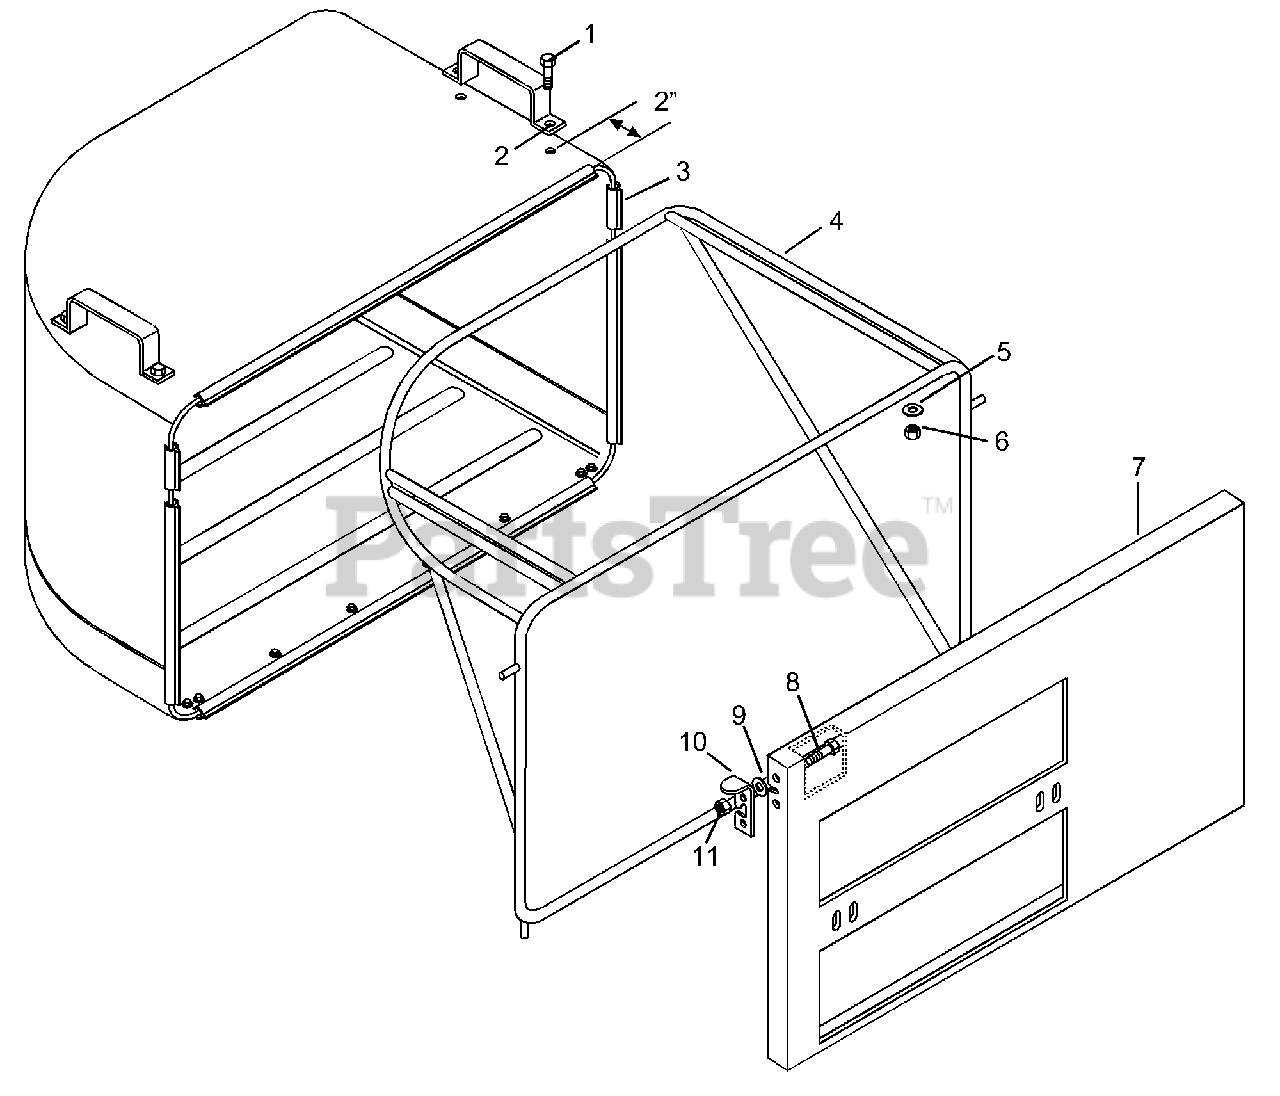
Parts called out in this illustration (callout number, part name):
1	Bolt-Hex .25-20 x 1.00 Grade 5
2	Handle-Hopper
3	Assembly-Pan Head & Catcher
4	Frame-Catcher
5	Washer-Handle
6	Nut-Locking-Nylon .250-20 Grade 2
7	Support-Grass Catcher w/Decal
8	Screw-Machine 10-24 x .625
9	Washer-Spring 1/4
10	Latch-Catcher Left Hand
10	Latch-Catcher Right Hand
11	Nut-Locking 10-24
